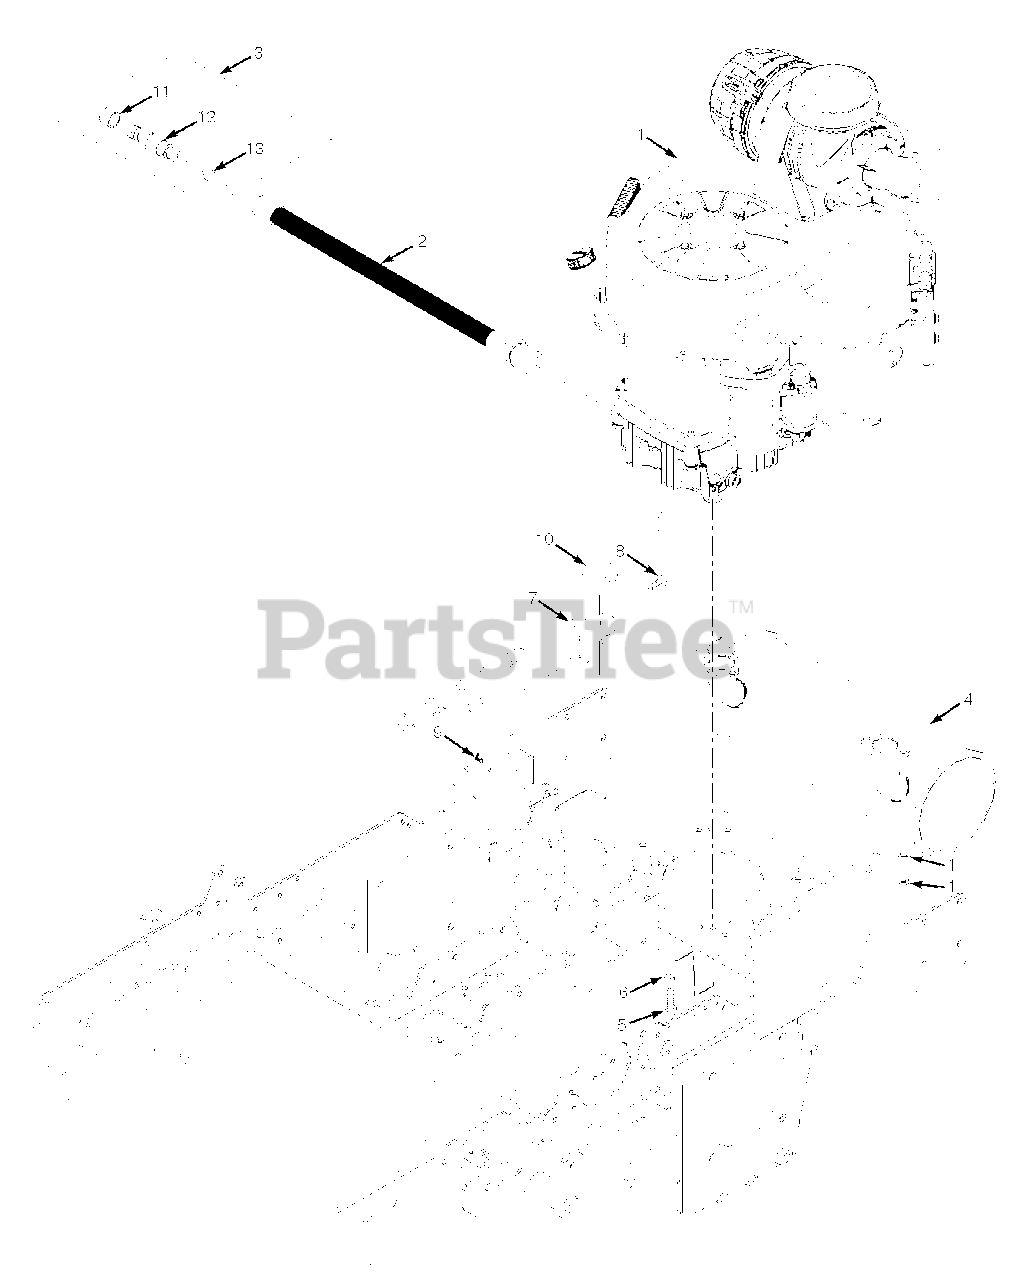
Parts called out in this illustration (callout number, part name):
1	Engine, Kawasaki FX850
1	Engine, Kohler CV940
1	Engine, Kawasaki FX921
1	Engine, Briggs & Stratton 36BV
2	Hose, Oil Drain, Kawasaki
2	Hose, OIl Drain, Briggs & Stratton
2	Hose, Oil Drain, Kohler
3	Valve Assembly, Oil Drain
4	Muffler, Kawasaki FX850 - SCZ
4	Muffler, Kawasaki FX921 - SCZ
4	Muffler, Briggs & Stratton - SCZ
4	Pipe, Muffler Extention (Briggs & Stratton Only)
4	Muffler, Kohler - SCZ
5	Bolt, Hex Head 3/8-16 x 1-1/4" (Kawasaki)
5	Bolt, Hex Head 5/16-18 x 1-1/2" (Briggs & Stratton)
5	Nut, Serrated Flange 5/16-18 (Briggs & Stratton)
6	Lockwasher, 3/8" Spring (Kawasaki)
7	Bracket, Oil Drain Hose
8	Screw, #8-32 x 1/2"
9	Nut, Elastic Stop #8-32
10	Bushing, Thick Panel Snap
12	O-Ring
